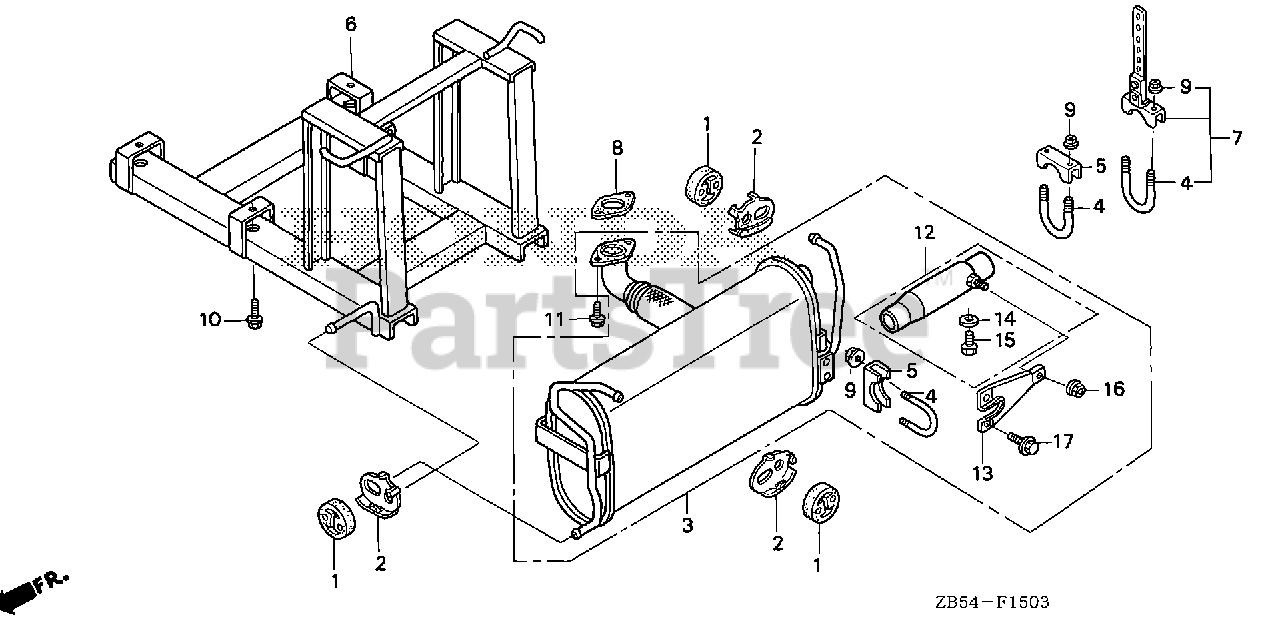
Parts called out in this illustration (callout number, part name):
1	RUBBER, EX. PIPE MOUNTING (60X50X20)
2	BRACKET, MOUNTING
4	BOLT, MUFFLER TAIL PIPE
5	CLAMP, MUFFLER TAIL PIPE
6	STAY, MUFFLER *NH105* (MAT BLACK)
7	BRACKET ASSY., MUFFLER TAIL PIPE
8	GASKET, MUFFLER
9	NUT, FLANGE (8MM)
10	BOLT, FLANGE (8X16) Use from Engine SN 1000016.
11	BOLT, FLANGE (8X20) Use up to Engine SN 1609606.
12	ARRESTER, SPARK
13	BRACKET A, MUFFLER
14	WASHER, PLAIN (10MM)
15	BOLT, HEX. (10X12)
16	NUT, HEX. (10MM)
17	BOLT, FLANGE (6X12) Use up to Engine SN 1543277.
